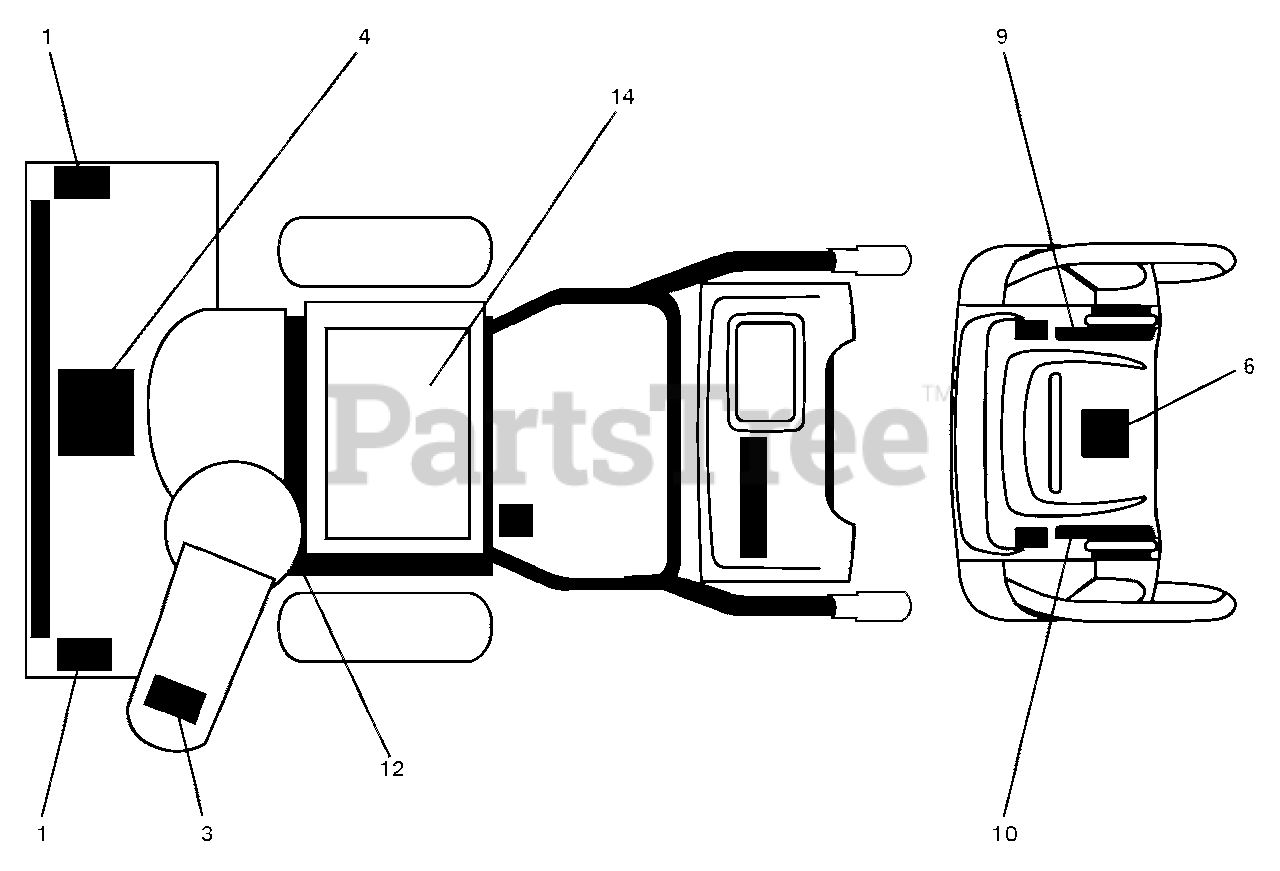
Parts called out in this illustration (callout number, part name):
1	DECAL.AUGER.SAFETY.
3	DECAL.CHUTE.SAFETY.
4	DECAL.AUGER."
6	DECAL.CONSOLE.INSTRUCTION
9	DECAL.CONS.RT.SPD/LEV/PWRST
12	DECAL.BELT.GUARD.
14	DECAL.FENDER
